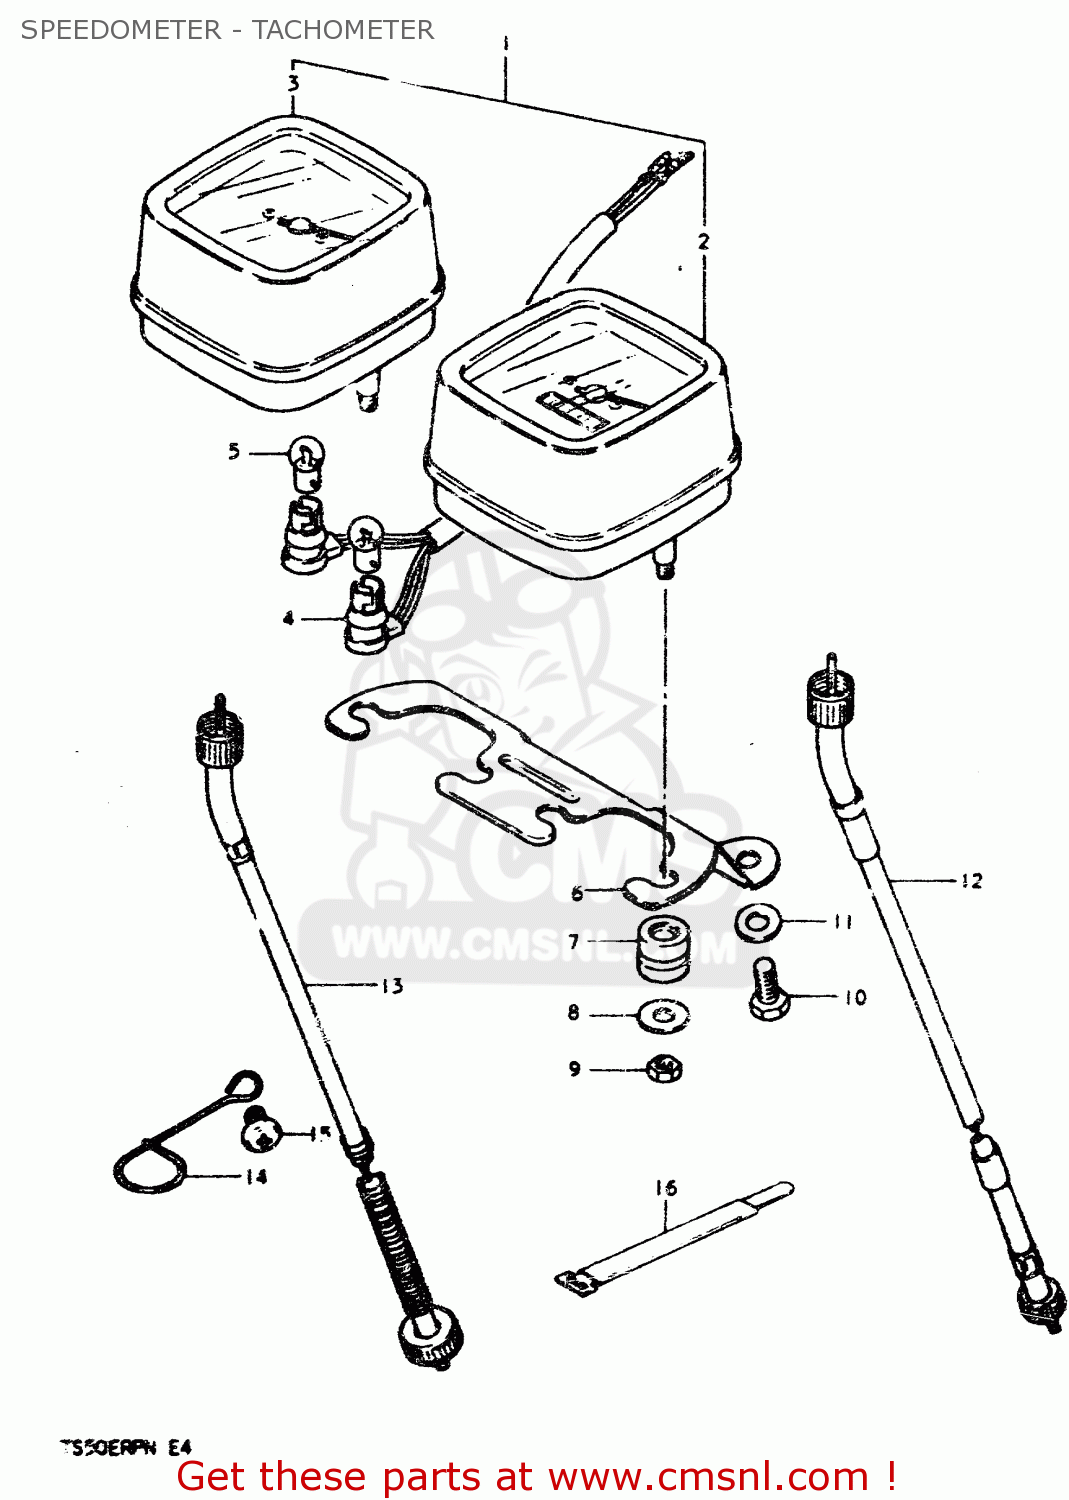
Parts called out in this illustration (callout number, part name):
1	SPEEDOMETER & TACHOMETER ASSY
2	SPEEDOMETER
3	TACHOMETER
4	SOCKET,METER
5	BULB(6V1.7W,STANLEY,A61A)
6	BRACKET
7	CUSHION
8	WASHER,METER
9	NUT
10	BOLT 8X12
11	WASHER
12	CABLE, SPEEDOMETER
13	CABLE ASSY, TACHOMETER
14	CLIP
15	SCREW
16	CLAMP
